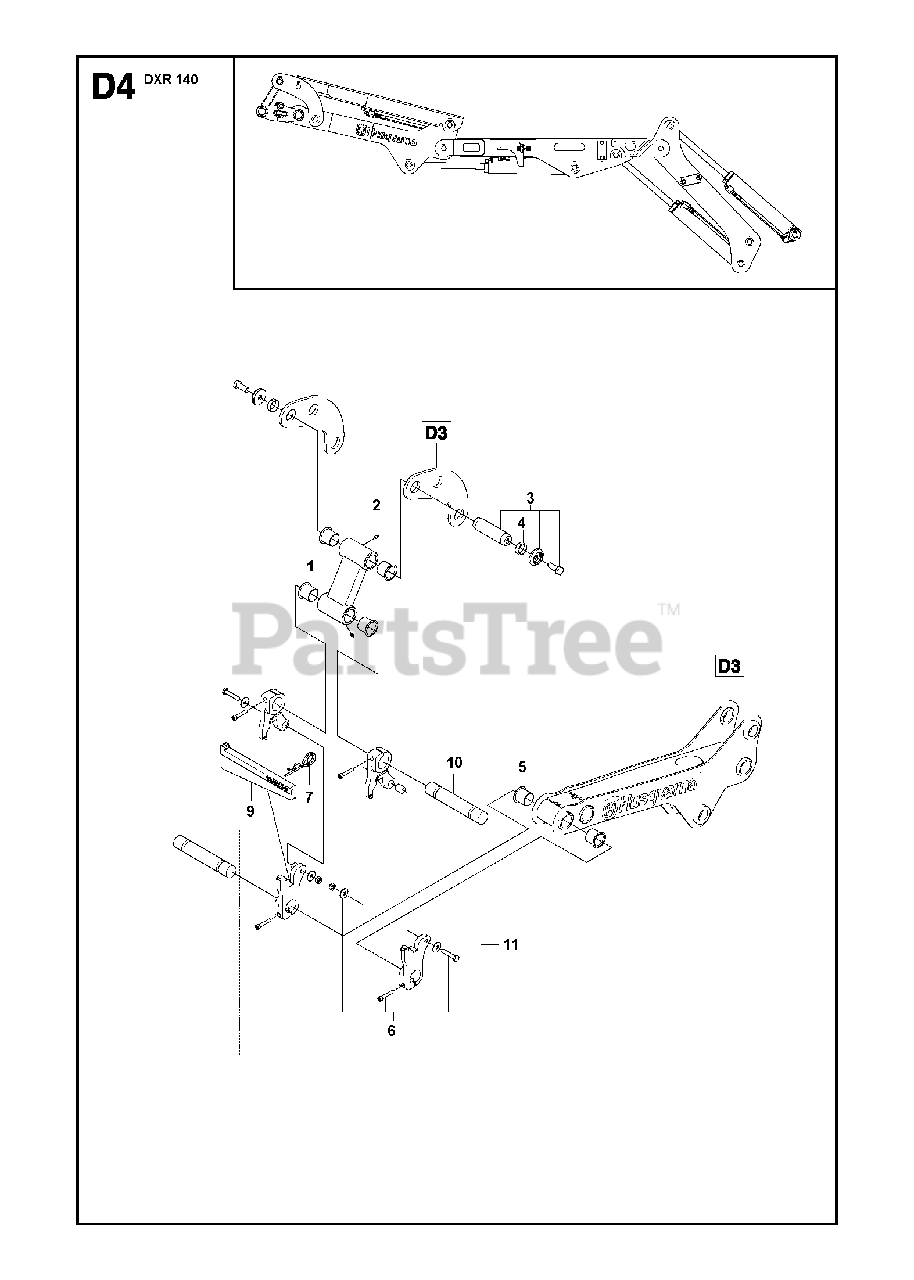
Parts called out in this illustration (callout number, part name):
6	KITvalid for old tool hitch
7	CLIPvalid for old tool hitch
9	WEDGEvalid for old tool hitch
10	SHAFTvalid for old tool hitch
11	HITCHvalid for old tool hitch
